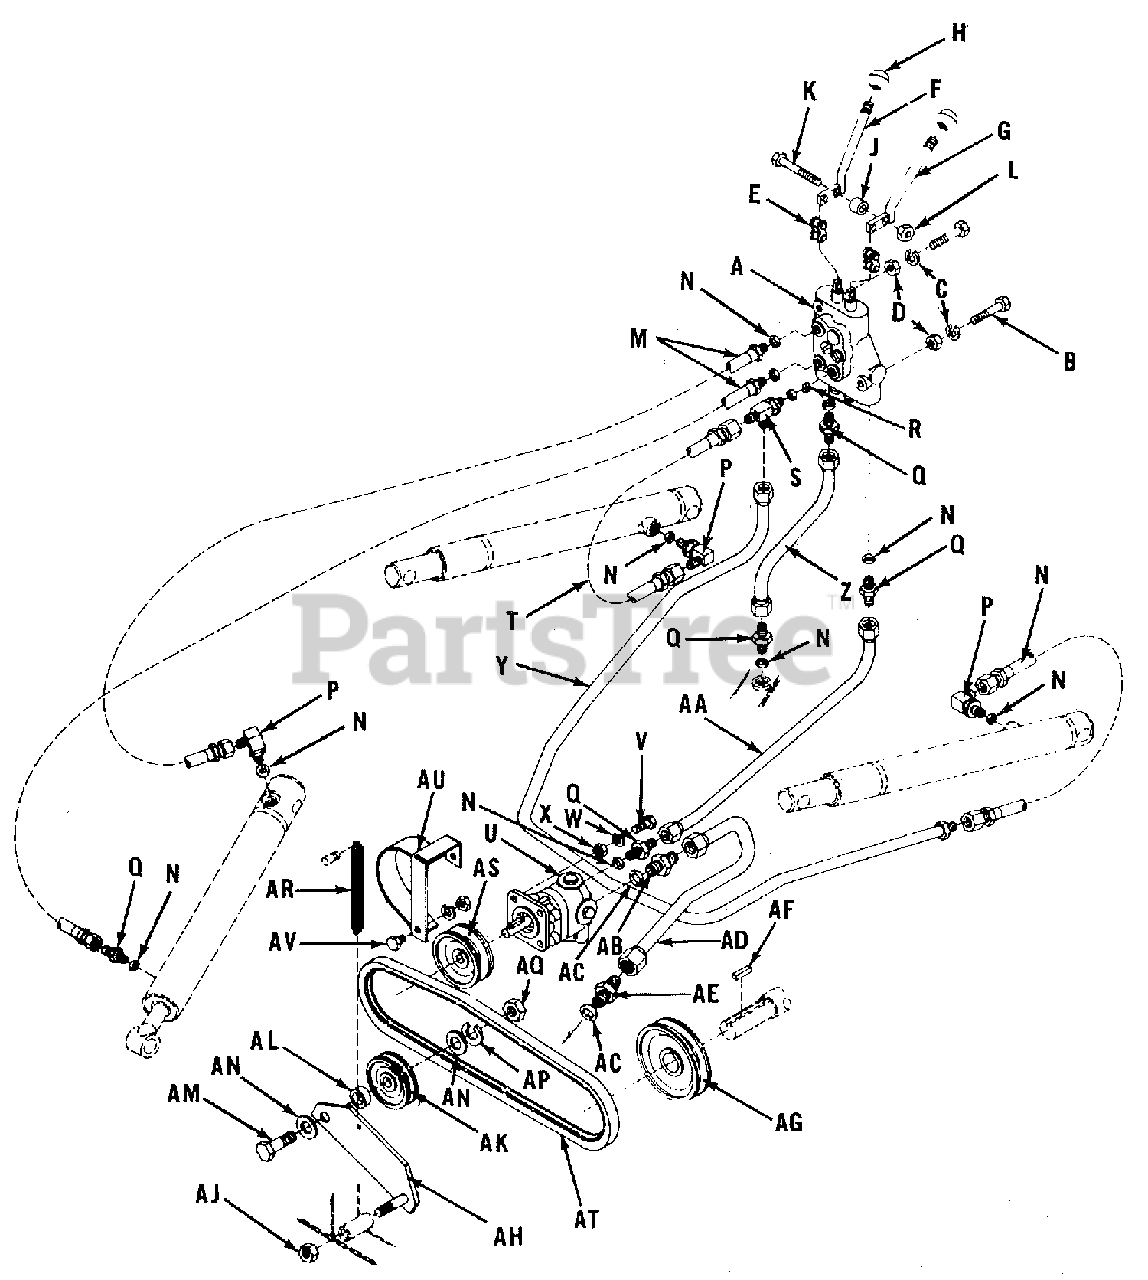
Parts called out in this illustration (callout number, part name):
A	CONTROL VALVE ASSEMBLY
B	CAPSCREW, Hex, 1/4"-20 NC x 2"
C	WASHER, Lock, 1/4"
D	NUT, Hex, Full, 1/4"-20 NC
E	LINK, Chain
F	HANDLE, Bucket
G	HANDLE, Lift
H	KNOB, Control Handle
K	CAPSCREW, Hex, 1/4"-28 NF x 2-3/4"
L	NUT, Hex, Full Lock, 1/4"-28 NF
M	HOSE ASSEMBLY
N	RING, "O"
P	CONNECTOR, 90 Degree Elbow
Q	CONNECTOR, Straight
R	RESTRICER, Orifice Plate
S	CONNECTOR, Run Tee
T	HOSE ASSEMBLY
U	PUMP ASSEMBLY
V	CAPSCREW, Hex, 5/16"-18 NC x 1"
W	WASHER, Lock, 5/16"
X	NUT, Hex, Full, 5/16"-18 NC
Y	TUBE ASSEMBLY, Lift
Z	TUBE ASSEMBLY, Return
AA	TUBE ASSEMBLY, Pressure
AB	CONNECTOR, Straight
AC	RING, "O"
AD	TUBE ASSEMBLY, Suction
AE	CONNECTOR, Filter
AH	LEVER ASSEMBLY, Idler
AJ	NUT, Hex, Full Lock, 3/8"-24 NF
AK	PULLEY, Idler
AM	CAPSCREW, Hex, 1/2"-13 NC x 2"
AN	WASHER, Plain, 1/2" Standard
AP	WASHER, Lock, 1/2"
AQ	NUT, Hex, Full, 1/2"-13 NC
AR	SPRING, Tension
AT	BELT, "V"
AV	CAPSCREW, Hex, 1/4"-20 NC x 1/2"
AW	WASHER, Lock, 1/4"
AX	NUT, Hex, Full, 1/4"-20 NC
